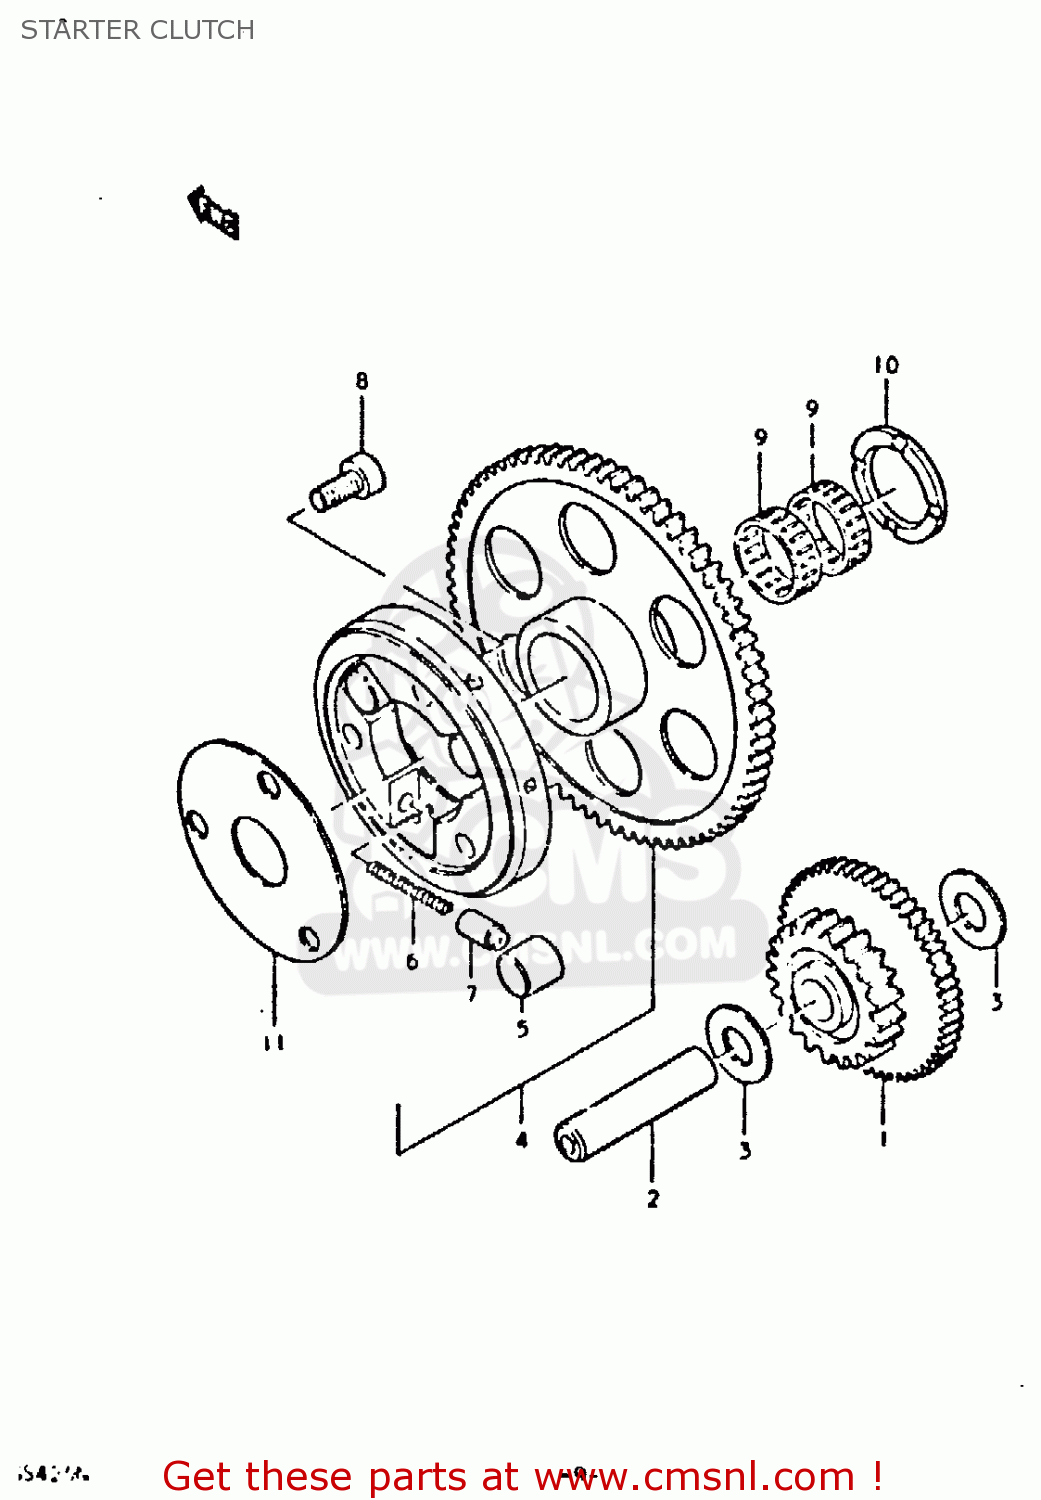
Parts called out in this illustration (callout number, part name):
1	GEAR,STARTER IDLER
2	PIN(7.4X13X56)
3	WASHER(13.3X25X0.85)
4	CLUTCH SET,STARTER
5	ROLLER(15X13)
6	SPRING
7	PIECE,PUSH
8	BOLT
9	BEARING(25X29X9.9)
10	WASHER(25X38X2.5)
11	SHIM,STARTER CLUTCH HUB
